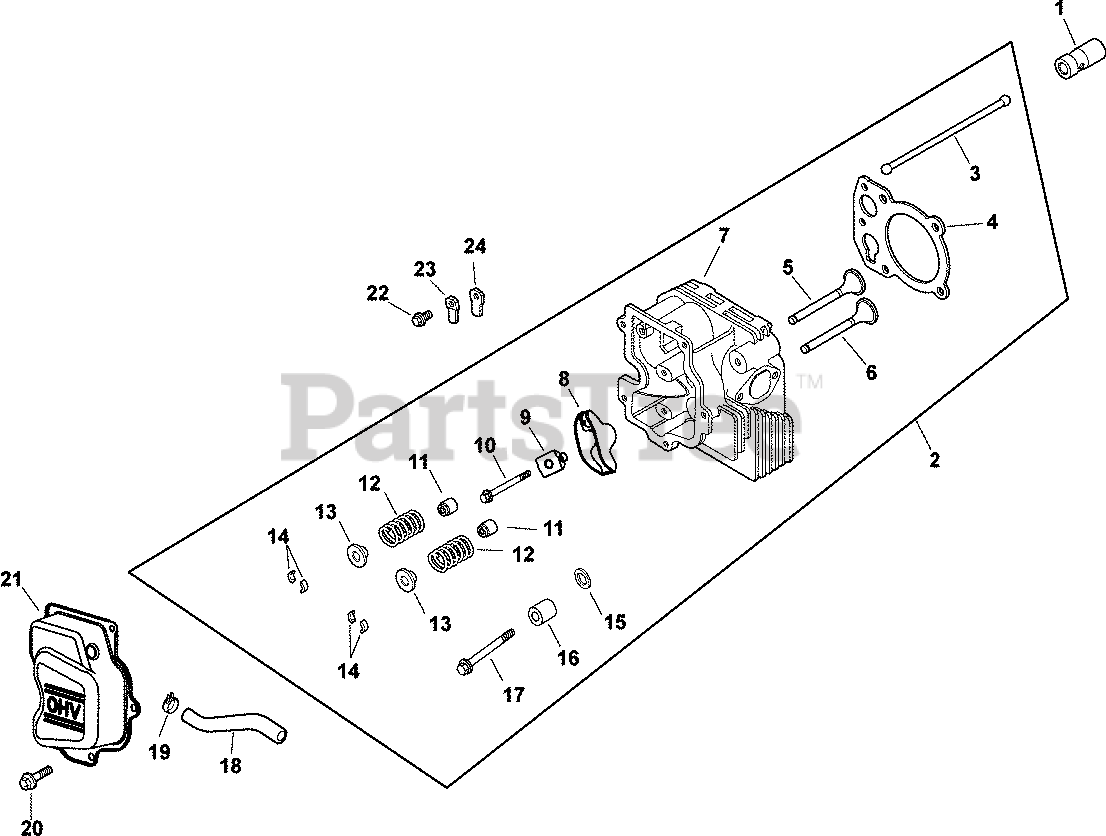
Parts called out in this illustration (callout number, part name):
1	LIFTER, HYDRAULIC VALVE-USE 25 351 10-S
2	KIT, CYLINDER HEAD
3	ROD, PUSH
4	GASKET, CYLINDER HEAD
5	VALVE, EXHAUST
6	VALVE, INTAKE
7	KIT, HEAD, CYLINDER
8	ARM, ROCKER
9	PIVOT, ROCKER ARM
10	SCREW, FLG M6X1.0X34
11	SEAL, VALVE STEM - (#2503214S)
12	SPRING, VALVE
13	RETAINER, VALVE SPRING - USE 25 173 28-S
14	KIT, RETAINER
15	WASHER, FLAT 13/32"
16	SPACER, HEAD BOLT EXHAUST PORT
17	SCREW, CYLINDER HEAD (M10 X 80)
18	HOSE
19	CLAMP, HOSE (KM)-USE 25 237 31-S
20	SCREW,FLG THD FRM M6X1.0X16-(#25086397S)
21	COVER, ROCKER
22	SCREW, FLG THD FRM M5X.8X10
23	RETAINER, REED
24	REED, BREATHER
1232630-S	HOSE, BREATHER
1275574-S	KIT, ROCKER ARM
